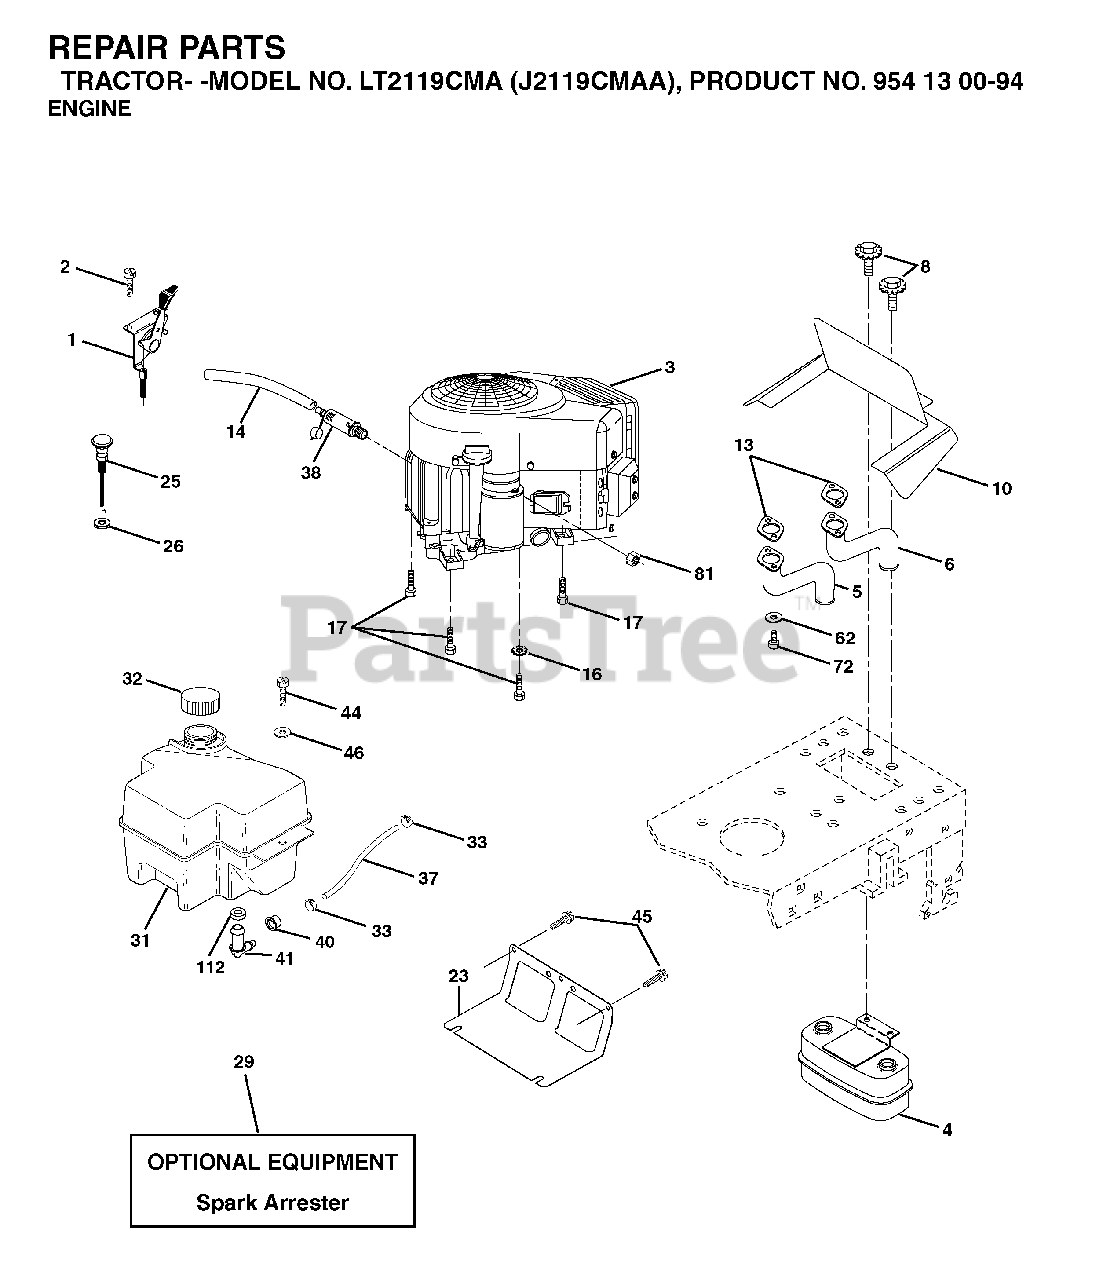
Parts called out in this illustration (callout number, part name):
1	THROTTLE CABLE
2	SCREW
4	MUFFLER.TWIN.CYL.LOW.TONE
5	TUBE MANIFOLD LH
6	EXHAUST TUBE RH
8	BOLT, 5/16-18 X 1 3/4
10	SHIELD.BROWNING.B&S
13	GASKET.MUFFLER
14	TUBE, DRAIN OIL ASM.
16	LOCKWASHER
23	SHEILD.BROWNING.DBR.GUARD
25	REPL BY 532 1754-40
26	NUT KEPS 3/8 - 24 UNF
29	ARRESTER SPARK (OPTIONAL)
31	GAS TANK 2GAL
32	FUEL CAP
33	HOSE CLAMP
37	LINE.FUEL.20
38	PLUG DRAIN OIL EASY
40	GROMMET T
41	STEM FUEL TANK
44	SCREW HEXWSHR 1/4-20X3/4
45	SCREW, 3/8-16X3/4
62	LOCKWASHER
72	SCREW
81	NUT
112	BUSHING OUTLET T
